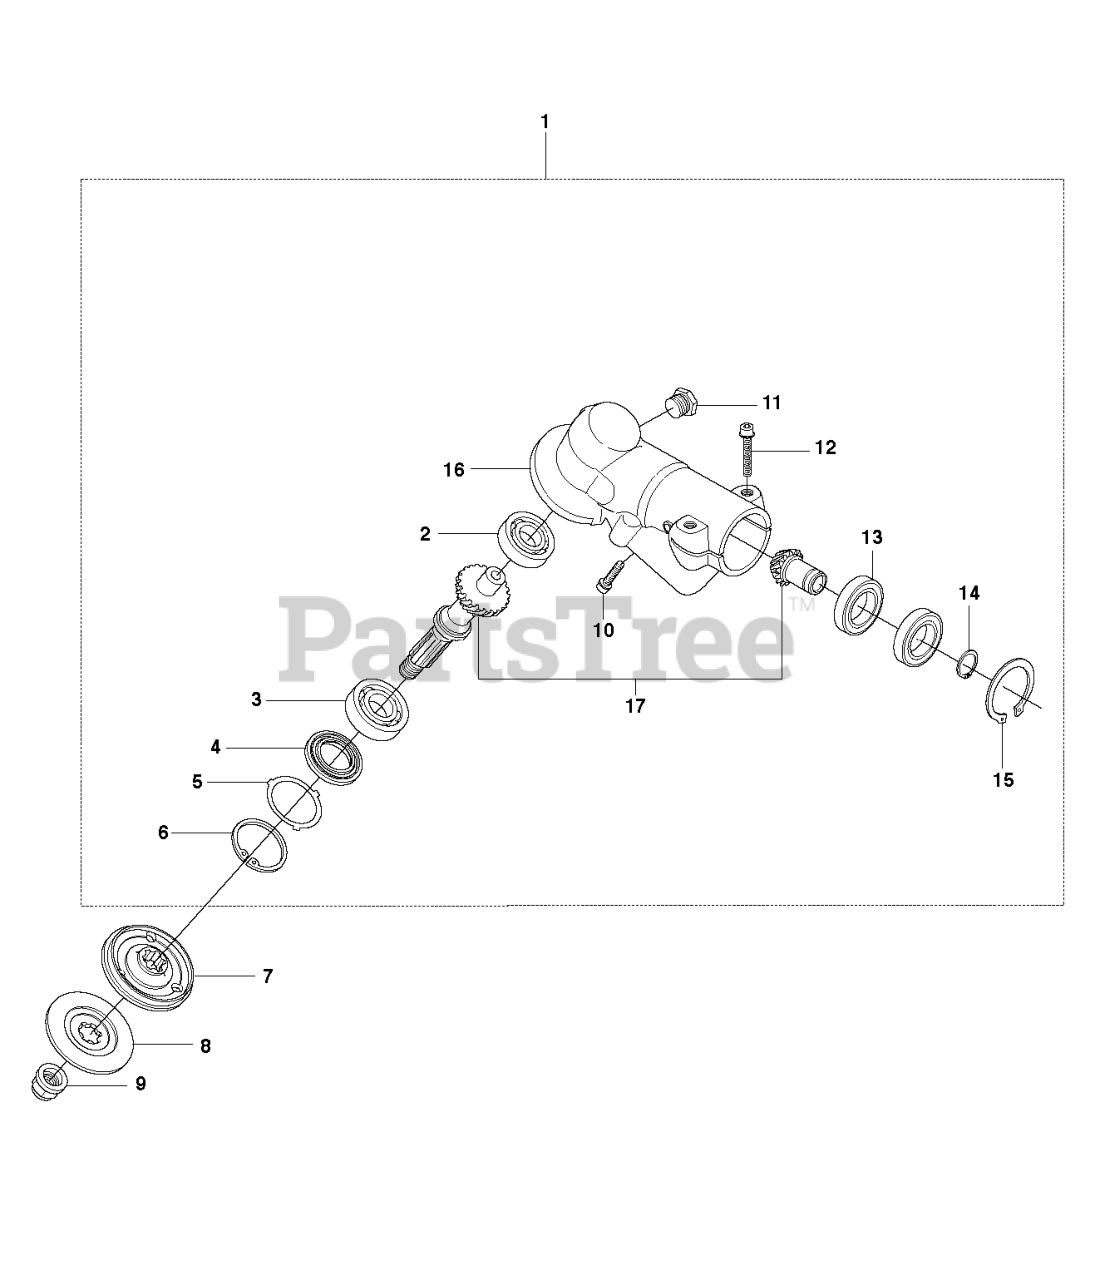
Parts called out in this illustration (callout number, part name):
1	RP_GEAR HOUSING ASSY
2	BALL BEARING
3	BALL BEARING
6	RETAINING RING SGH 35
7	DRIVER
8	SUPPORT FLANGE
13	BALL BEARING
14	RETAINING RING SGA 15
15	RETAINING RING
16	GEAR HOUSING
17	RP_SPARE PARTS KIT
